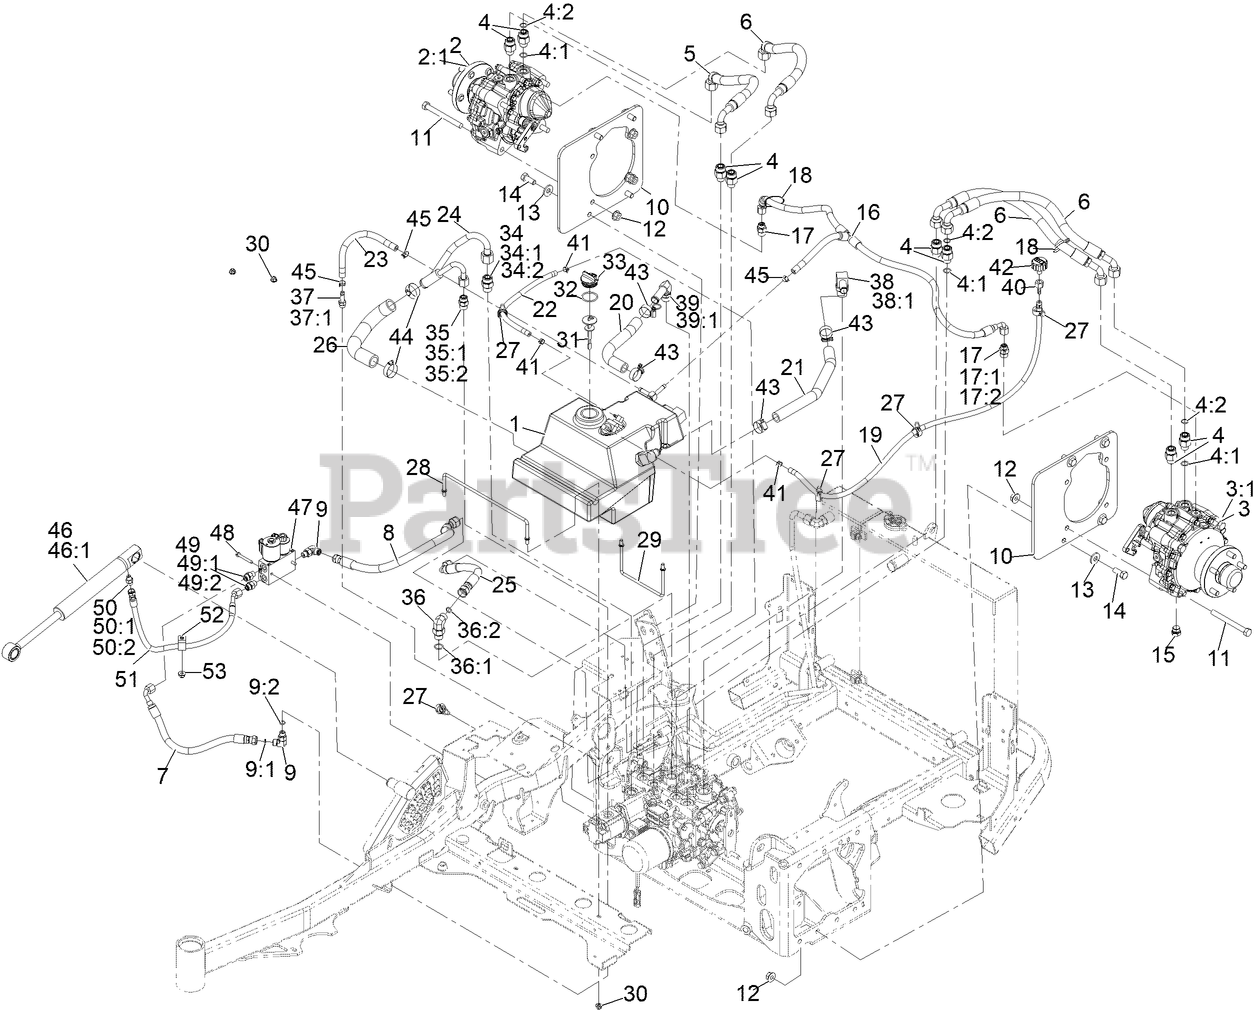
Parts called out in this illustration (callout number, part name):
1	HYD RESERVOIR ASM
2	MOTOR-HYD, RH
2:1	5 STUD WHEEL HUB KIT
3	MOTOR-HYD, LH
3:1	5 STUD WHEEL HUB KIT
4	FITTING-STRAIGHT
4:1	O-RING
4:2	O-RING
5	HOSE ASM
6	HOSE ASM
7	HOSE ASM
8	HOSE ASM
9	FITTING-ELBOW, 90 DEG
9:1	O-RING
9:2	O-RING
10	PLATE-MOTOR
11	SCREW-HH
12	NUT-HHF
13	WASHER-SPRING
14	SCREW-HH
15	PLUG-MAGNETIC
16	TEE HOSE ASM
17	FITTING-STRAIGHT
17:1	O-RING
17:2	O-RING
18	TIE-CABLE
20	HOSE-RETURN
21	HOSE-RETURN
24	TUBE ASM
25	HOSE ASM
26	HOSE-SUCTION
27	CLIP-TIE
28	ROD-SUPPORT, HYD TANK
29	ROD-SUPPORT, HYD TANK
30	NUT-HF, NI
31	DIPSTICK
32	O-RING
33	PLUG-PLASTIC
34	FITTING-STRAIGHT
34:1	O-RING
34:2	O-RING
35	FITTING-STRAIGHT
35:1	O-RING
35:2	O-RING
36	FITTING-ELBOW, 90 DEG
36:1	O-RING
36:2	O-RING
37	ADAPTER-STRAIGHT
37:1	O-RING
38	FITTING-ELBOW, 90
38:1	O-RING
39	FITTING-90
39:1	O-RING
40	FITTING-STRAIGHT
41	CLAMP-HOSE
42	BREATHER
43	CLAMP-HOSE
44	CLAMP-HOSE
45	CLAMP-HOSE
46	CYLINDER-LIFT
46:1	KIT, CYL REPAIR
47	DECK LIFT VALVE ASM
48	SCREW-HWHTF
49	FITTING-STRAIGHT
49:1	O-RING
49:2	O-RING
50	FITTING-HYD, STRAIGHT
50:1	O-RING
50:2	O-RING
51	HOSE ASM
52	CLIP-LOOM
53	NUT-HF, NI
